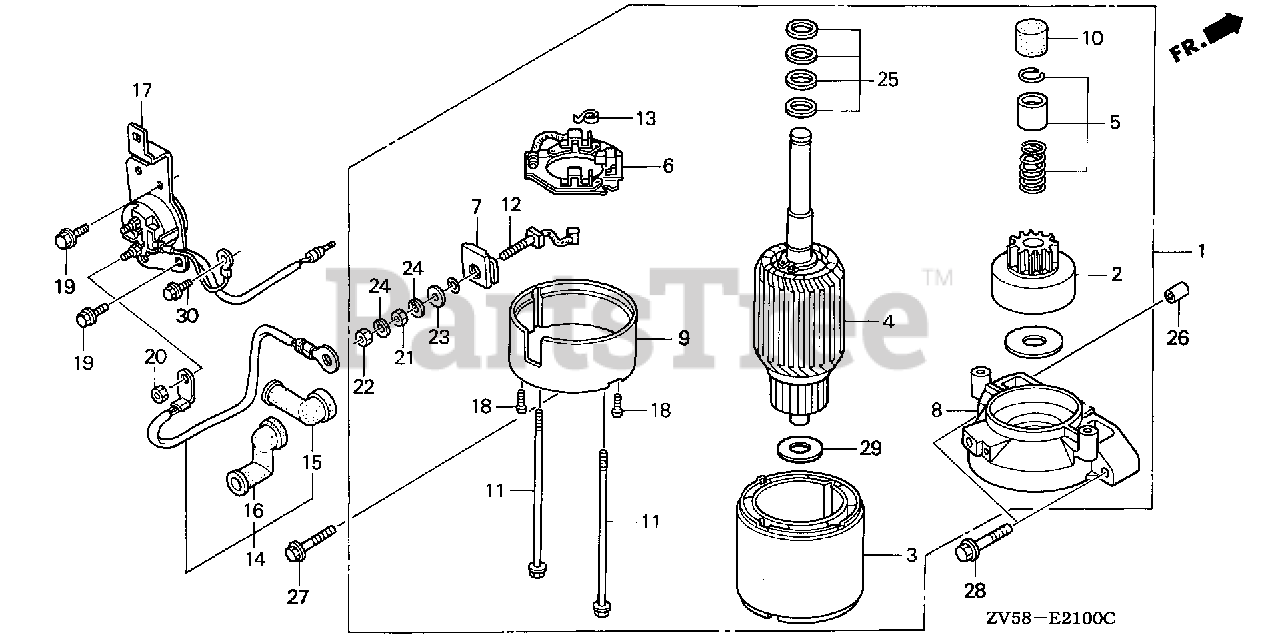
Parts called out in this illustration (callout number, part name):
1	MOTOR ASSY., STARTER
2	CLUTCH, OVERRUNNING
5	STOPPER SET, PINION
6	HOLDER, BRUSH
8	BRACKET, FR.
9	BRACKET, RR.
10	CAP, STOPPER
11	BOLT, THROUGH
13	SPRING, BRUSH
14	WIRE, MAGNETIC SWITCH (120MM)
15	COVER, STARTER MOTOR TERMINAL
16	COVER, MAGNETIC SWITCH TERMINAL
17	SWITCH ASSY., STARTER MAGNETIC
18	SCREW (4MM)
19	BOLT, FLANGE (6X12)
20	NUT, HEX. (6MM)
23	WASHER (1)
24	WASHER (2)
25	WASHER SET, THRUST
26	PIN A, DOWEL (10X16)
27	BOLT, FLANGE (6X28)
28	BOLT, FLANGE (8X45) (NOT AVAILABLE)
28	BOLT, FLANGE (8X45)
29	WASHER, RR.
30	BOLT, FLANGE (6X12)
30	BOLT, FLANGE (6X12) (CT200)
